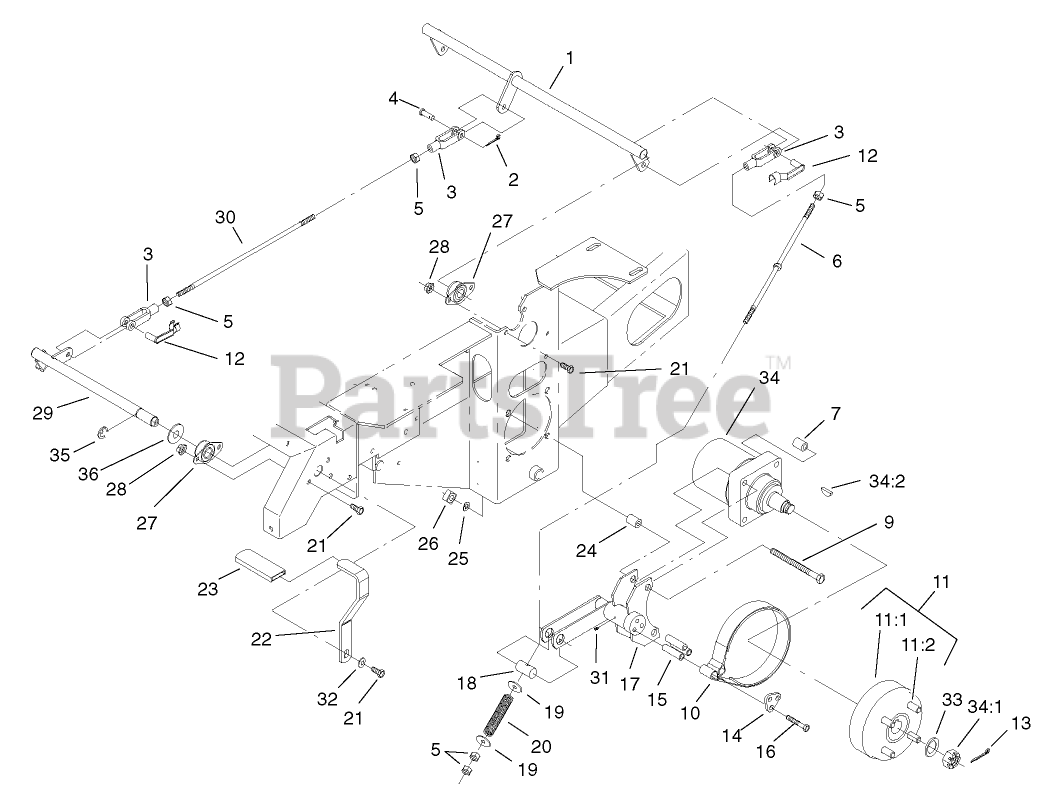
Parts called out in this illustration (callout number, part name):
1	CRANK-BRAKE, PARK
2	PIN-COTTER
3	YOKE-LINKAGE, BRAKE
4	PIN-CLEVIS
5	NUT-HEX
6	ROD-BRAKE
7	SPACER-WHEEL
9	SCREW-HH
10	BAND-BRAKE
11	WHEEL HUB ASM
11:1	HUB-WHEEL
11:2	STUD-WHEEL
12	Pin-Spring, Clevis
13	PIN-COTTER
14	RETAINER-BAND, BRAKE
15	SPACER
16	SCREW-HH
17	BRACKET-BRAKE
18	PIN-TRUNION
19	WASHER-FLAT
20	SPRING-BRAKE
21	SCREW-HH
22	HANDLE-BRAKE, PARK
23	GRIP-LEVER
24	SPACER-WHEEL
25	WASHER-LOCK
26	NUT-SQUARE
27	BEARING-FLANGE, SIDE
28	NUT-HHF, WHIZ
29	Shaft-Brake, Parking
30	LINKAGE-HANDLE, BRAKE
31	FITTING-GREASE
32	WASHER-BELLEVILLE
33	WASHER-SPACER
34	MOTOR-WHEEL
34:1	NUT-HH
34:2	KEY-WOODRUFF
35	E-RING
36	WASHER-FLAT
